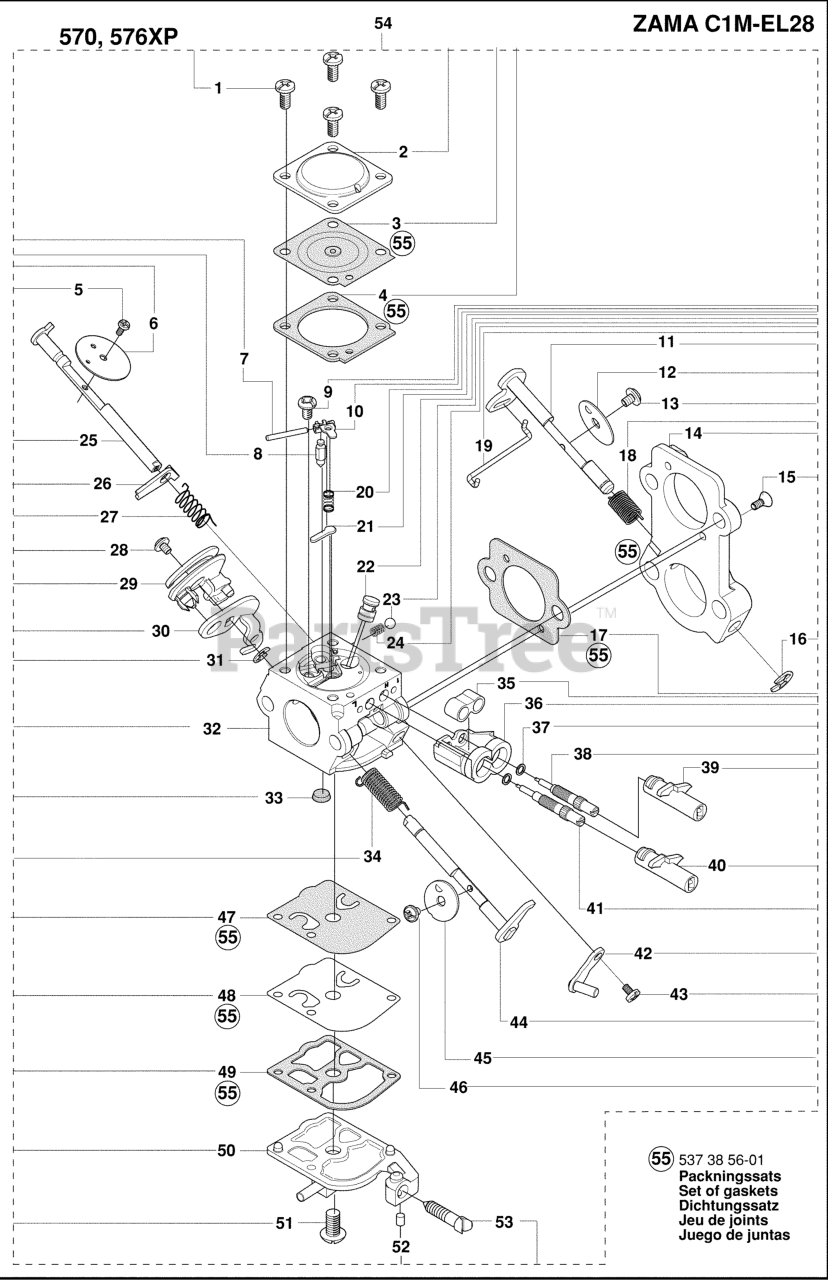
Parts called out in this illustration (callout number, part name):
6	CHOKE FLAP
7	PIN RETAINING SCREW
8	INLET NEEDLE
12	THROTTLE FLAP
14	RP CARBURETOR
25	CHOKE SHAFT
32	RP CARBURETOR
38	NEEDLE HIGH SPEED
41	LOW SPEED NEEDLE
44	THROTTLE SHAFT
47	PUMP DIAPHRAGM
54	RP CARBURETOR
55	GASKET SET
